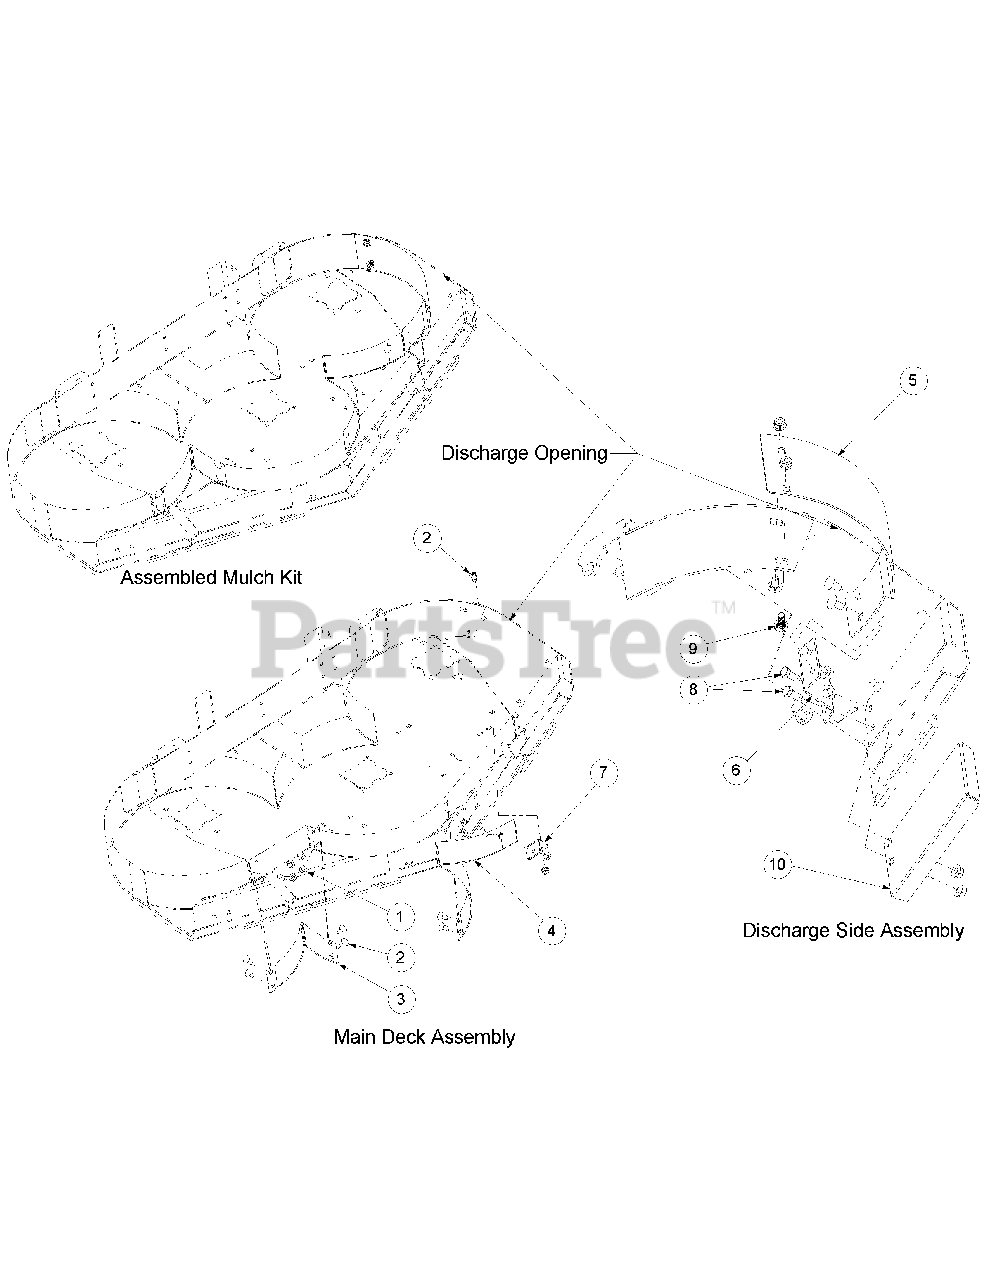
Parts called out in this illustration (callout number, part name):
1	Flange Lock Hex Nut, 3/8-16
2	Carriage Bolt, 3/8-16 x .75
3	Mulching Baffle, LH
4	Mulching Baffle, Center
5	Mulching Baffle, RH
6	Mulching Bracket, RH
7	Mulching Bracket, Center
8	HHCS, 3/8-16 x .88
9	Carriage Bolt, 3/8-16 x 1.0
10	Mulch Plug Baffle
